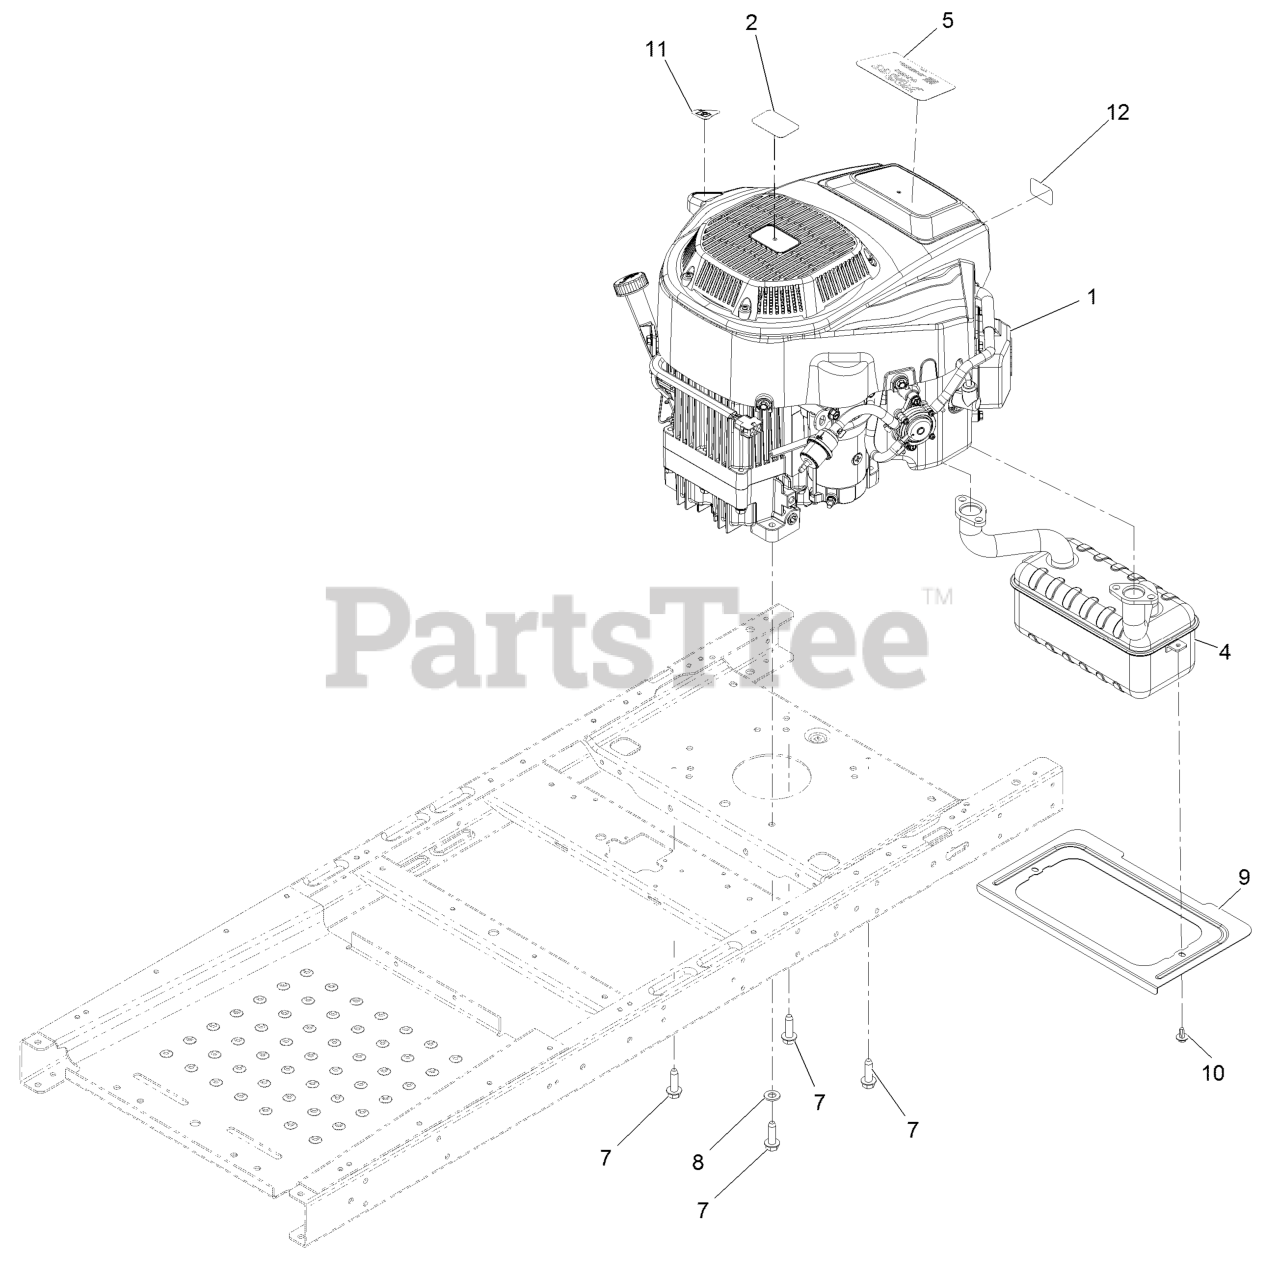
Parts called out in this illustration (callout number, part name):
4	MUFFLER
5	DECAL-ENGINE DISPLACEMENT
7	SCREW-THD
8	WASHER-FLAT
9	SHIELD-HEAT
10	SCREW-HHFTF
11	DECAL-DRAIN, OIL
12	PLACARD-INTAKE, EXMARK
